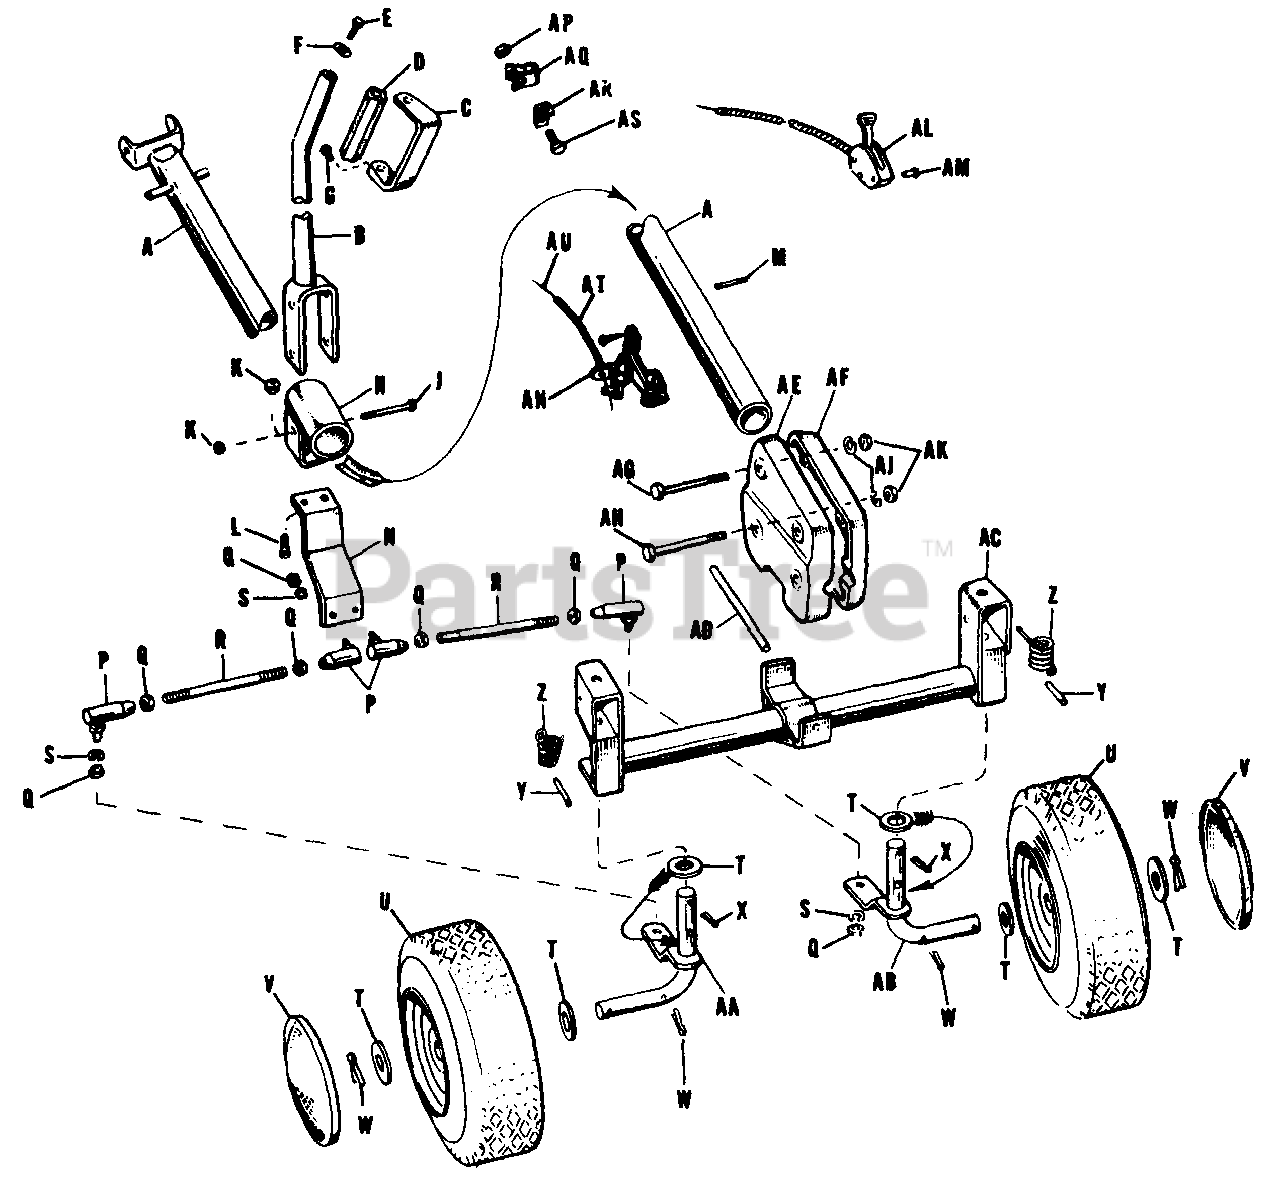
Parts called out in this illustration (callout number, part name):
A	Frame Assembly, Front
B	Handle Assembly
C	Guard, Handle
D	Grip, Handle
G	Screw, Hex Hd., Self Tapping, #10 x 5/8
H	Pivot Assembly, Steering
J	Screw, Hex Hd. Cap, 3/8-16 x 3 1/4
K	Lock Nut, Hex, 3/8-16
L	Screw, HexCap, 3/8-16 x 7/8
M	Pin, Roll, 7/32 x 1" Long
N	Arm, Lever
P	Joint, Ball
Q	Nut, Full Hex, 3/8-24
S	Lock Washer, 3/8
U	Wheel & Tire Assembly
V	Hub Cap, Front
W	Pin, Cotter, 3/16 x 1 1/4
X	Pin, Cotter, 5/32 x 1
Y	Pin, Roll, 5/16 x 1 1/4
Z	Spring, Torsion
AA	Spindle Assembly, R.H.
AB	Spindle Assembly, L.H.
AC	Axle Assembly, Front
AD	Pin, Pivot
AE	Support, Front, R.H.
AF	Support, Front, L.H.
AG	Screw, Hex Cap, 3/8-16 x 3 1/4
AH	Screw, Hex Cap, 3/8-16 x 3 3/4
AJ	Lock Washer, 3/8
AK	Nut, Full Hex, 3/8-16
AL	Throttle Control Assembly
AM	Screw, Self Tapping, 10-24 x 1
AN	Lever Assy. Choke
AP	Nut, Hex Full
AS	Screw, Cap Hex
